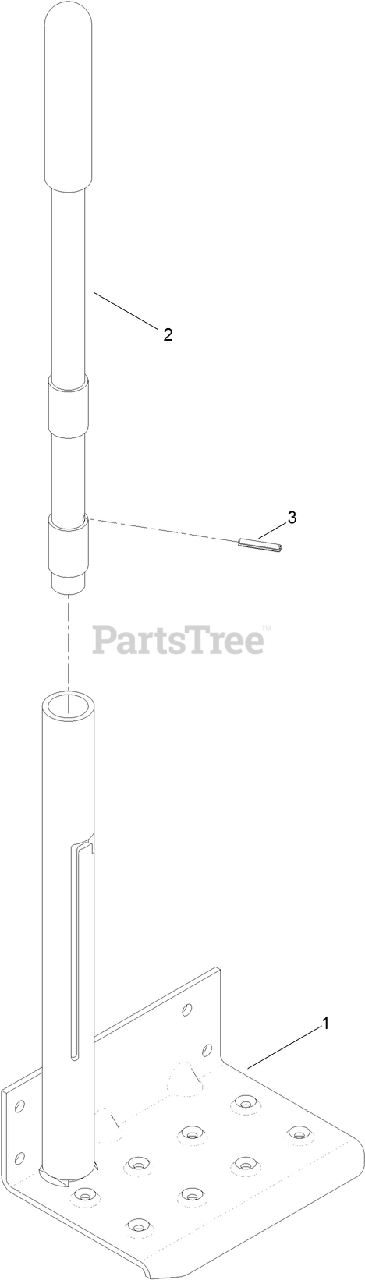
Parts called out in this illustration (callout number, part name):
1	HANDLE-LOWER
2	HANDLE ASM
3	PIN-SPRING
